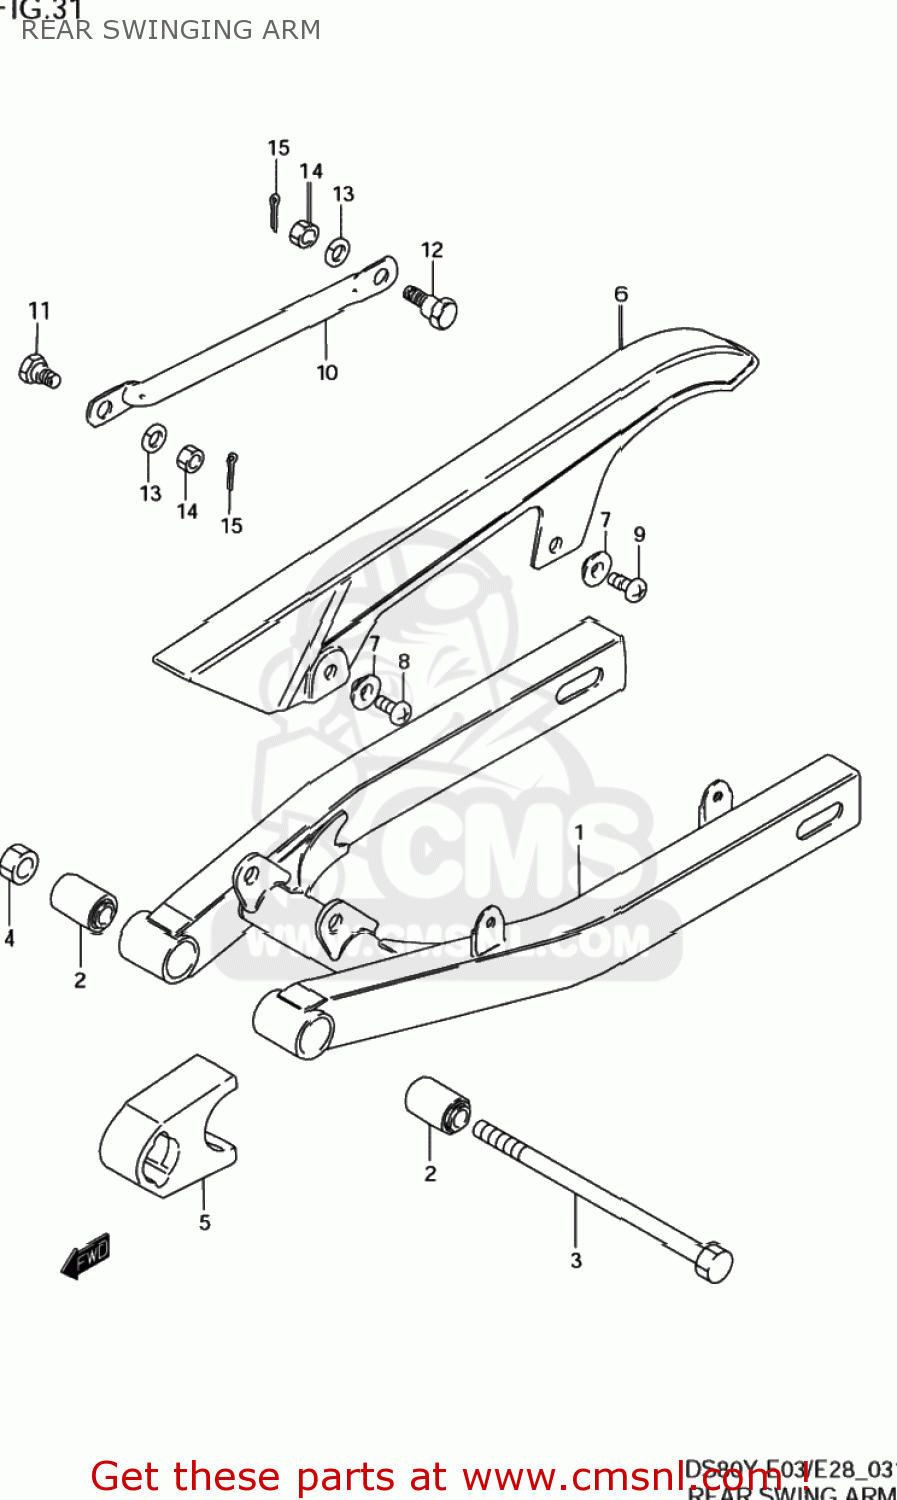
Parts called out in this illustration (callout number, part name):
1	SWINGINGARM ASSY,RR
2	BUSH
3	SHAFT,RR SWINGINGARM PIVOT
4	NUT
5	BUFFER,CHAIN TOUCH DEFENSE
6	CASE,CHAIN
7	WASHER
8	SCREW
9	SCREW
10	TORQUELINK,RR
11	BOLT(8X22)
12	BOLT(8X26.5)
13	LOCK WASHER
14	NUT
15	PIN 20X20
